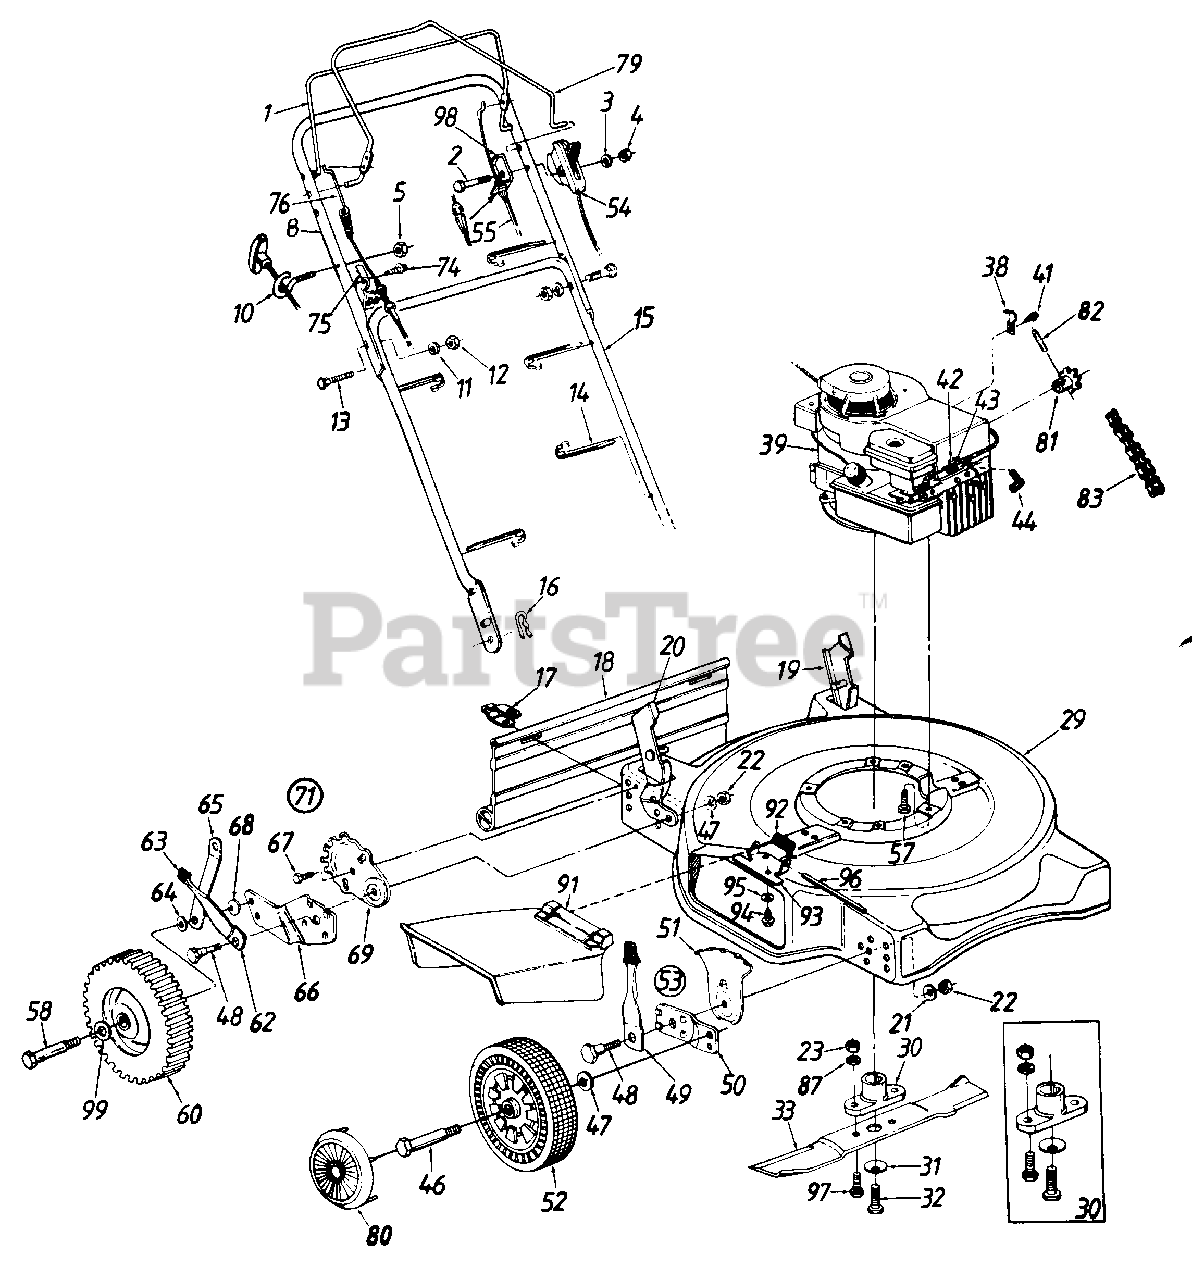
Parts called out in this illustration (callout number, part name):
1	Control Handle
2	Hex Bolt 1/4-20 x 1.875" Lg.
3	Spr. Wash. .265" I.D. x .562" O.D.
4	Hex Nut 1/4-20 Thd.*
5	Hex L-Nut 1/4-20 Thd.
8	Upper Handle
10	Rope Guide
11	L-Wash. 5/16" I.D.*
12	Hex Nut 5/16-18 Thd.*
13	Curved Carriage Bolt 5/16-18 x 1.38" Lg
14	Cable Tie
15	Lower Handle
16	Hairpin Cotter
17	Hinge Clip
18	Rear Flap
19	Handle Bracket Ass'y.-L.H.
20	Handle Bracket Ass'y.-R.H.
21	Bell-Wash. .39" I.D. x 1.38"
22	Hex Nut 3/8-16 Thd.
23	Hex Nut 3/8-24 Thd.
29	22" Deck Ass'y.
30	Blade Adapter Kit
31	Bell-Wash..39" I.D.
32	Hex Bolt 3/8-24 x 1.5" Lg.
33	22" Blade
38	Cable Clamp
39	Engine
41	Hex B-Tap Scr. #10 x .38"
42	Cable Clamp
43	Hex AB-Tap Scr. #8 x 38" Lg.
44	Spark Plug Boot
46	Front Axle Bolt
47	Bell-Wash. .400" I.D. x .88"
48	Shld. Bolt .50" Dia. x .357"
49	Spring Lever Ass'y. w/Knob
51	Height Adj. Plate
52	Front Wheel Ass'y. Comp.
53	Height Adj. Ass'y. Comp.-R.H.
54	Throttle Control Ass'y. Comp. 51.62" Lg.
55	Control Cable-39"
57	Hex L-Wash. Hd. Scr. 3/8-16 x 1.0" Lg.
58	Rear Axle Bolt
60	Rear Wheel Ass'y. Comp.
62	Spring Lever
63	Spring Lever Knob
64	Fl-Wash. .531" I.D. x .93"
67	Hex AB-Tap 1/4-.62" Lg.
68	Bell-Wash. .380" I.D. x .88"
69	Index Plate
71	Rear Height Adj. Ass'y.-R.H.
74	Hex Wash. AB-Tap Scr. 5/16 x.75" Lg.
75	Cable Brkt.
76	Clutch Cable w/Spring-33"
79	S.P. Bail Ass'y.
80	Hub Cap
81	10 Tooth Sprocket Ass'y.
82	Spring Pin Spir. 3/16" Dia. x 1" Lg.
83	#48 Chain 1/2" Pitch 50 Links
87	L-Wash. 3/8" I.D.*
91	Chute Deflector Ass'y.
92	Torsion Spring
93	Adapter Plate
94	Hex Self-Tap Scr. 1/4-20 x .5" Lg.
95	Bell-Wash. 1/4" I.D.
96	Hinge Pin
97	Hex Bolt 3/8-24 x 1" Lg.
98	Cable Mtg. Bracket
99	Fl-Wash. .531" I.D. x .93"
